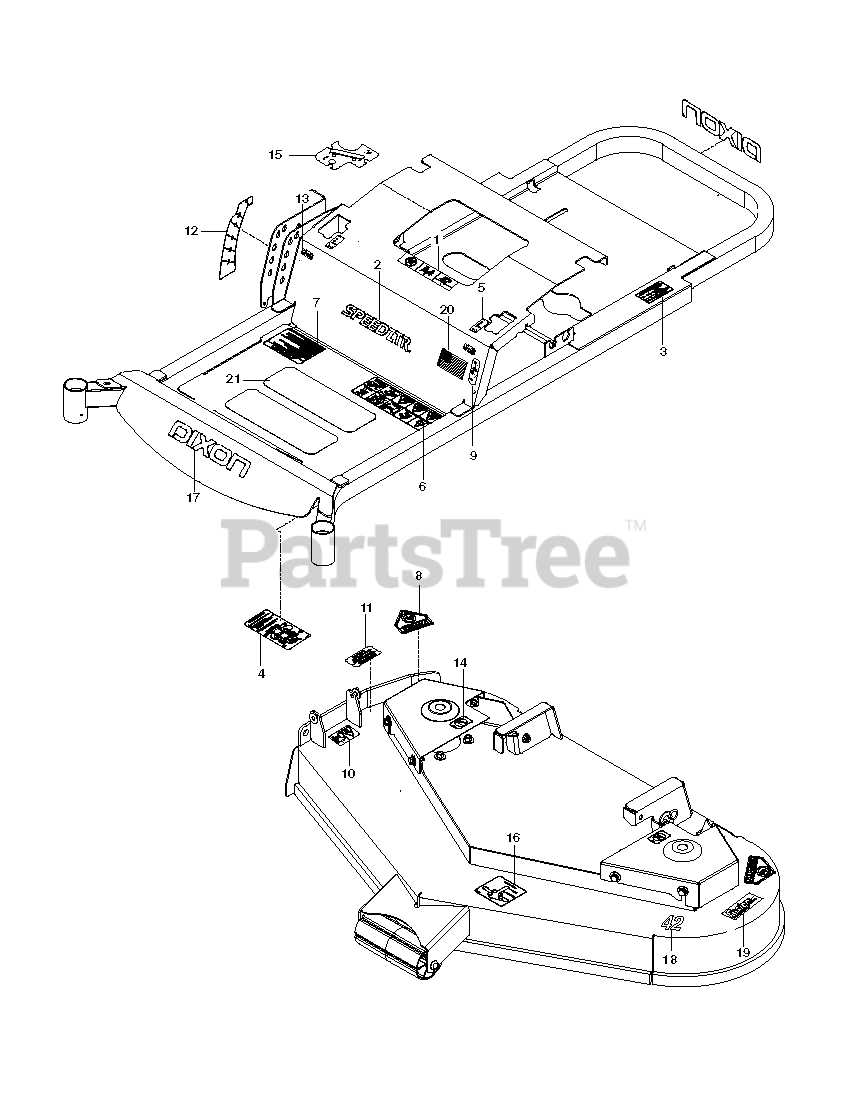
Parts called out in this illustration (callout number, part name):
2	DECAL, SPEEDZTR, 8"
3	DECAL, DO NOT MOUNT
4	DECAL, SERVICE
5	DECAL, MOTION CONTROL
6	DECAL, SAFETY WARNING
7	DECAL, WARNING
8	DECAL, CPSC
9	DECAL, PARK BRAKE
10	DECAL, EURO SEVERING
11	DECAL, DANGER
12	DECAL, HEIGHT
13	DECAL, TRACKING
14	DECAL, NO STEP
15	DECAL, CONTROLS PANEL, DIX
16	DECAL, BELT ROUTING
18	DECAL, 42
19	DECAL, FUSION
20	DECAL, FLAG
21	ANTI-SKID PAD
